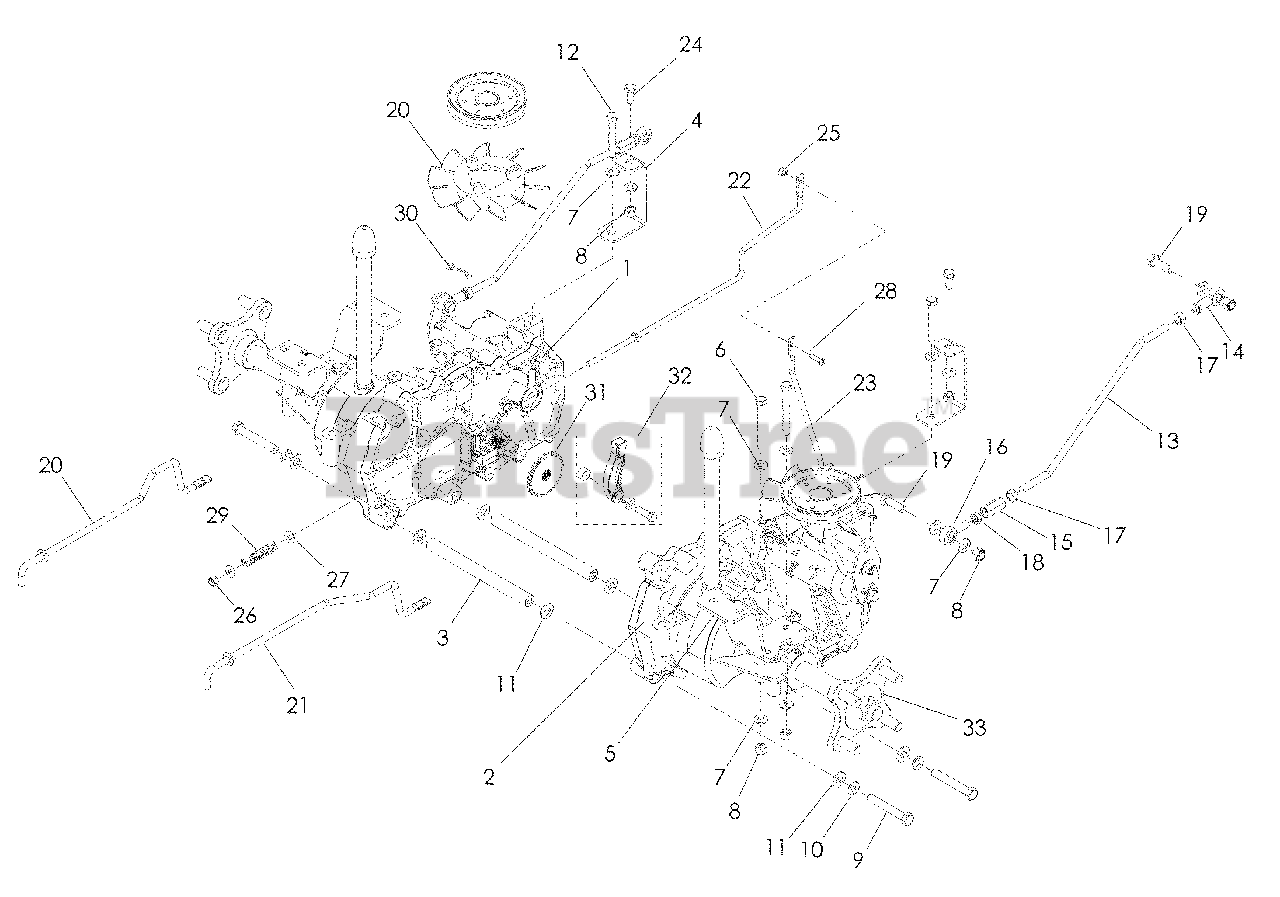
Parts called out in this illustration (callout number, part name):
3	SPACER TUBE
4	SUPPORT, EZT FRT
5	MOUNT, EZT RR
6	HCS 5/16-18 x 2¾
7	WASHER 5/16 SAE FLAT
8	NUT 5/16-18 HEX NYLOC
9	HCS 3/8-16 x 2½
10	WASHER 3/8 SPLT LK
11	WASHER 3/8 SAE FLT
12	HCS 5/16-18 x 2¼
13	ROD, MOTION CONTROL
14	ROD END RH
15	COUPLER, ROD END
16	ROD END MALE LH
17	NUT 5/16-24 HEX
18	NUT 5/16-24 HEX JAM LH
19	HCS 5/16-18 x 1
20	BLADE, FAN
21	LINK ARM, BYPASS
22	ROD, EZT BRAKE LT
23	ROD, EZT BRAKE RT
24	HCS 5/16-18 x ¾
25	NUT 10-24 HEX NYLOC
26	NUT ¼-20 HEX NYLOC
27	WASHER ¼ FLAT SAE
28	SCREW 10-24 x ¾ SLTD RD
29	SPRING, BRAKE ROD
30	HAIRPIN, COTTER
31	COG, BRAKE DISC
32	BRAKE ARM KIT
33	HUB KIT
